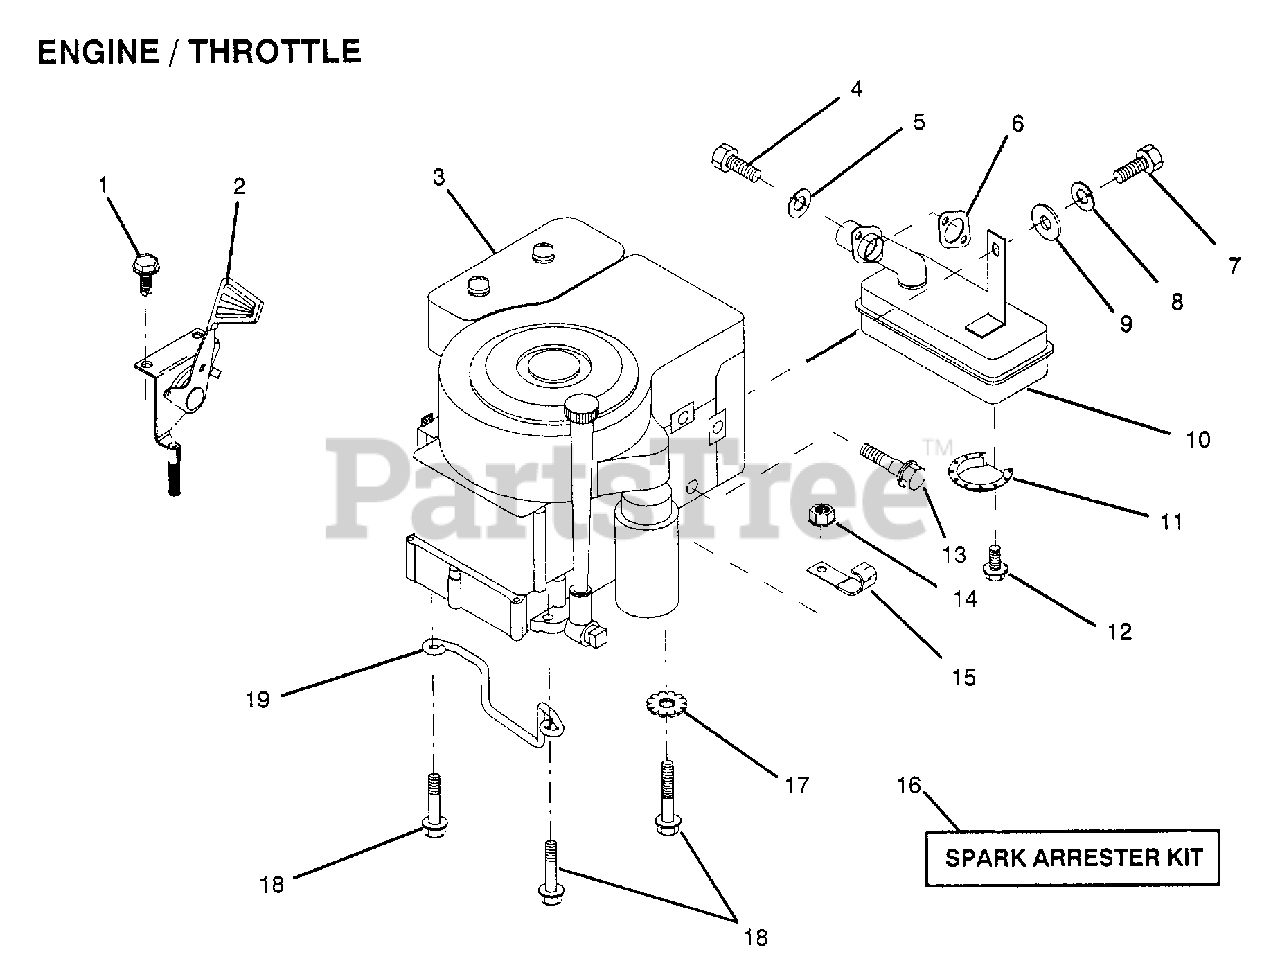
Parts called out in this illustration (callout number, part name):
1	SCREW
3	ENGINE BRIGGS AND STRATTON
4	SCREW
5	LOCKWASHER
8	LOCKWASHER
10	MUFFLER
11	MUFFLER
13	BOLT T
14	NUT
15	CLIP T
17	LOCKWASHER
18	SCREW LT
19	"KEEPER,DR BELT GR"
